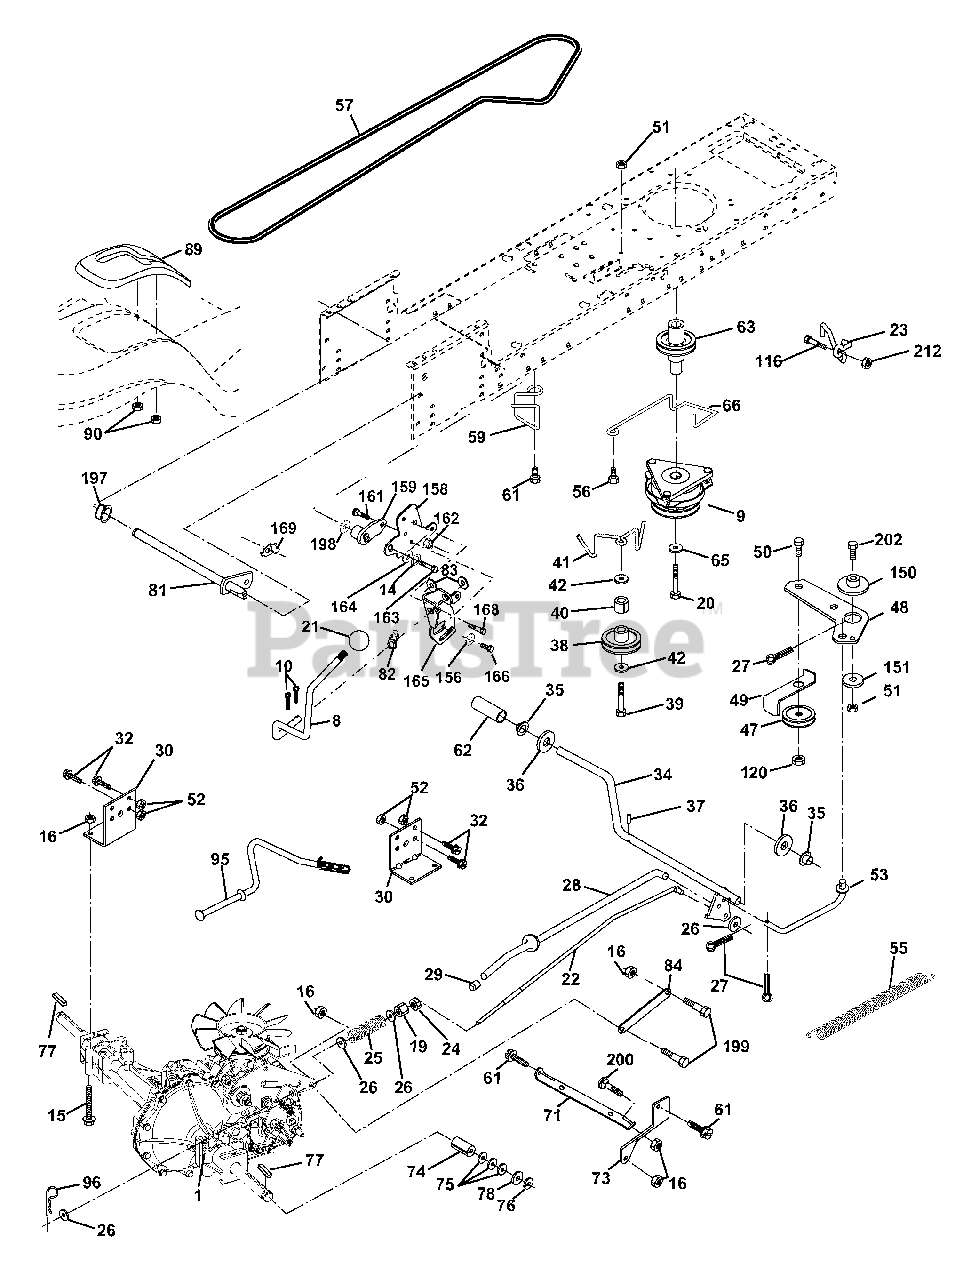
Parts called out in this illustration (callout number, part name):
8	Rod Shift Fender
9	Clutch Electric
10	Pin Cotter 1/8 x 1 CAD
14	Washer Lock Hvy Helical
15	Bolt Hex Flghd 5/16-18 Gr. 5
16	Nut Lock Hex W/Ins. 5/16-18 Unc
19	Nut Lock Hex W/Wsh 3/8-16 Unc
20	Bolt, Hex 7/16-20 x 4-1/4
21	Knob Deluxe
22	Rod, Brake Hydro
23	Bracket Asm. Anti Rotation
24	Locknut
25	Spring, Brake Rod
26	Washer
27	Pin Cotter 1/8 x 3/4 CAD.
28	Rod, Parking Brake
29	Cap, Parking Brake
30	Bracket, Transaxle
32	Bolt Hex Hd 5/16-18 Unc x 3/4
34	Shaft, Foot Pedal
35	Bearing, Nylon
36	Washer
37	Pin, Roll
38	Pulley, Composite, Flat
39	Bolt
40	Spacer Split
41	Keeper, Belt Idler Fool-Proof
42	Washer 13/32 x 13/16 x 12 Gauge
47	Pulley, Idler, V-Groove
48	Bellcrank Clutch Grnd Drv Stl
49	Retainer, Belt
50	Bolt
51	Nut
52	Nut Crown Lock 5/16-18
53	Link, Clutch
55	Spring, Return, Clutch
56	Screw 3/8-16 x 1
57	V-Belt, Ground Drive
59	Keeper, Center Span
61	Screw 3/8-16 x 3/4
62	Cover, Pedal
63	Pulley, Engine
65	Washer
66	Keeper Belt Engine Hydro
71	Strap Torque Lh Hydro
73	Strap Torque Rh Hydro
74	Spacer, Axle
75	Washer 25/32 x 1-1/4 x 16 Ga.
76	E-Ring
77	Key, Square
78	Washer 25/32 x 1-5/8 x 16 Ga.
81	Shaft Asm. Cross Hydro
82	Spring Torsion T/A
83	Washer 17/32 x 3/4 x 16 Ga.
84	Link Transaxle
89	Console, Shift
90	Nut Self-Thd Wsh-Hd 1/4
95	Control Asm. Bypass Hydro
96	Retainer Spring 1" Zinc/Cad
116	Bolt Rdhd 3/8-16 x 1
120	Nut Lock Flg. 3/8-16 Unc
150	Spacer Retainer
151	Washer 13/32 x 2 x 10 Ga.
156	Washer Srrted 5/16ID x 1.125
158	Bracket Shift Mount
159	Hub Tapered Flange Shift Lt
161	Bolt Rdhd Sqnk 1/4-20 x 3/4 Gr. 5
162	Nut Crownlock 1/4-20 Unc
163	Bolt Hex Fin 1/4-20 Unc x 1 Gr. 5
164	Washer 5/8 x .281 x 10 Ga
165	Bracket Pivot Lever
166	Screw 5/16-18 x 5/8
168	Bolt Shoulder 5/16-18 x .561
169	Plate Fastening Lt\
197	Nyliner Snap-In 5/8" ID
198	Washer Nyliner 7/8 ID x .105
199	Bolt Shoulder 5/16-18 Unc
200	Bolt Rdhd Sqnk 5/16-18 UNC x 1
202	Bolt Carr Sh 3/8-16 x 1-1/2 Gr.5
212	Nut Hex Flange Lock
